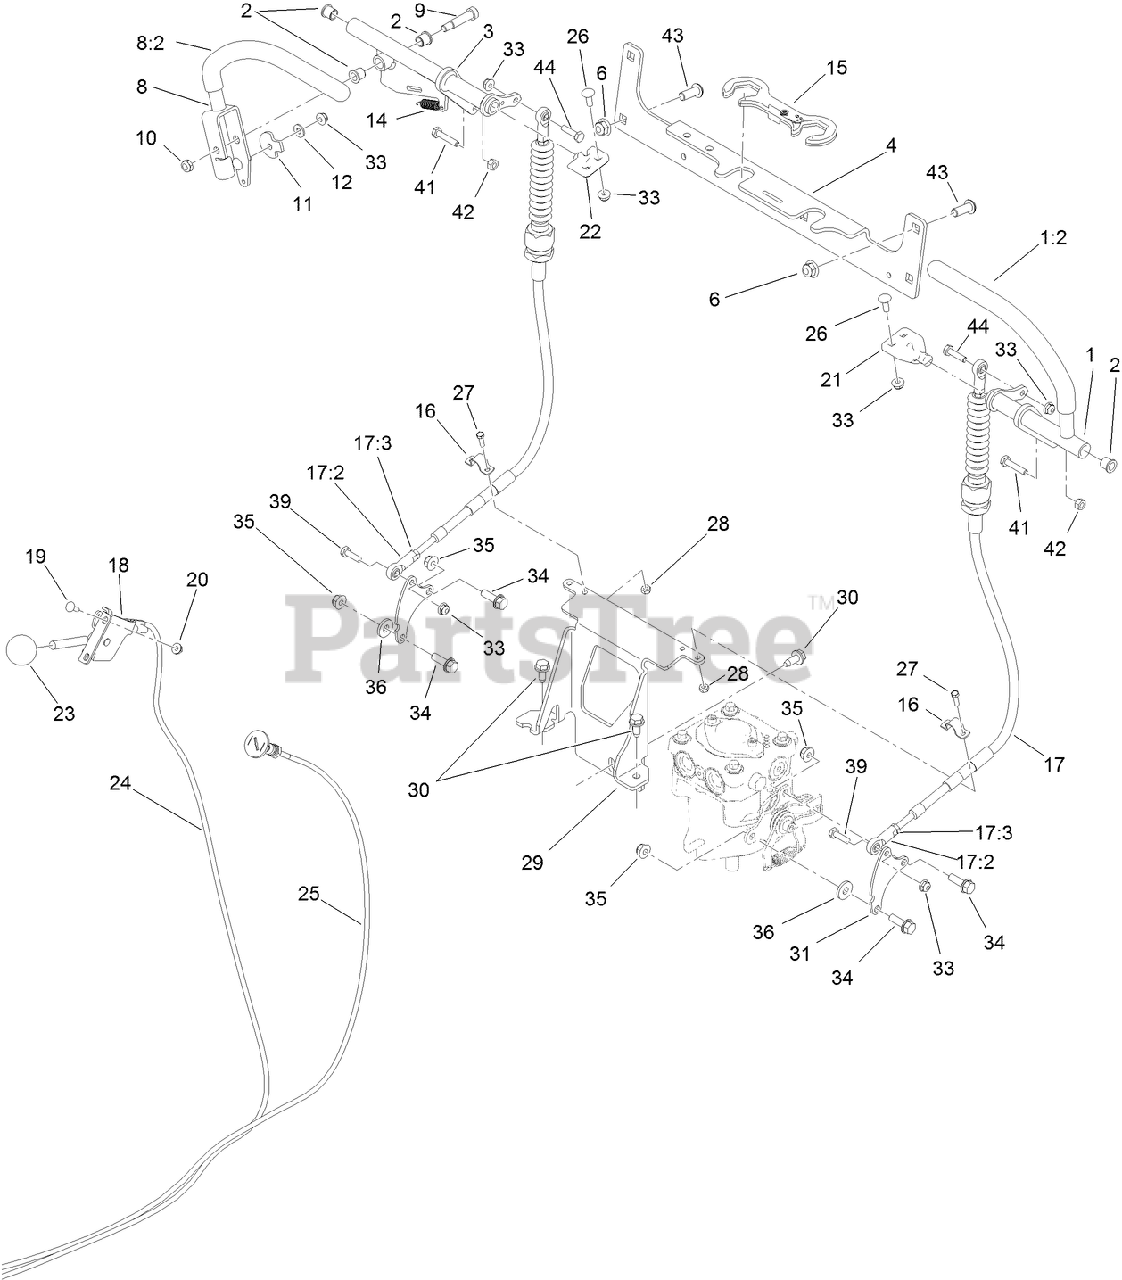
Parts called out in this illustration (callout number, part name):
1	LH LEVER ASM
2	BEARING
3	CONTROL-MOTION, RH
4	BRACKET-CROSS
6	NUT-HF, NI
8	LEVER-MOTION, RH
9	SCREW-HSH
10	NUT-LOCK, NI
11	CAM-LEVER
12	WASHER-FLAT
14	SPRING-EXTENSION
15	LOCK-CABLE
17	CABLE ASM
17:2	ROD END-BALL JOINT
17:3	NUT-JAM
18	LEVER-CONTROL
19	BOLT-CARR
20	NUT-LOCK, FLANGE
21	TAB-PIVOT, LH
22	TAB-PIVOT, RH
23	KNOB-BALL
24	CABLE-THROTTLE
25	CONTROL-CHOKE, PUSH/PULL
26	BOLT-CARR
28	NUT-LOCK, NI
29	BRACKET-MOUNT, CABLE
30	SCREW-HWHTF
31	PLATE-CONTROL, PUMP
33	NUT-HF
34	SCREW-HHF
35	NUT-HF, NI
36	WASHER-FLAT
39	SCREW-HH
41	SCREW-HH
42	NUT-HEX
43	SCREW-HSBH
44	SCREW-HH
